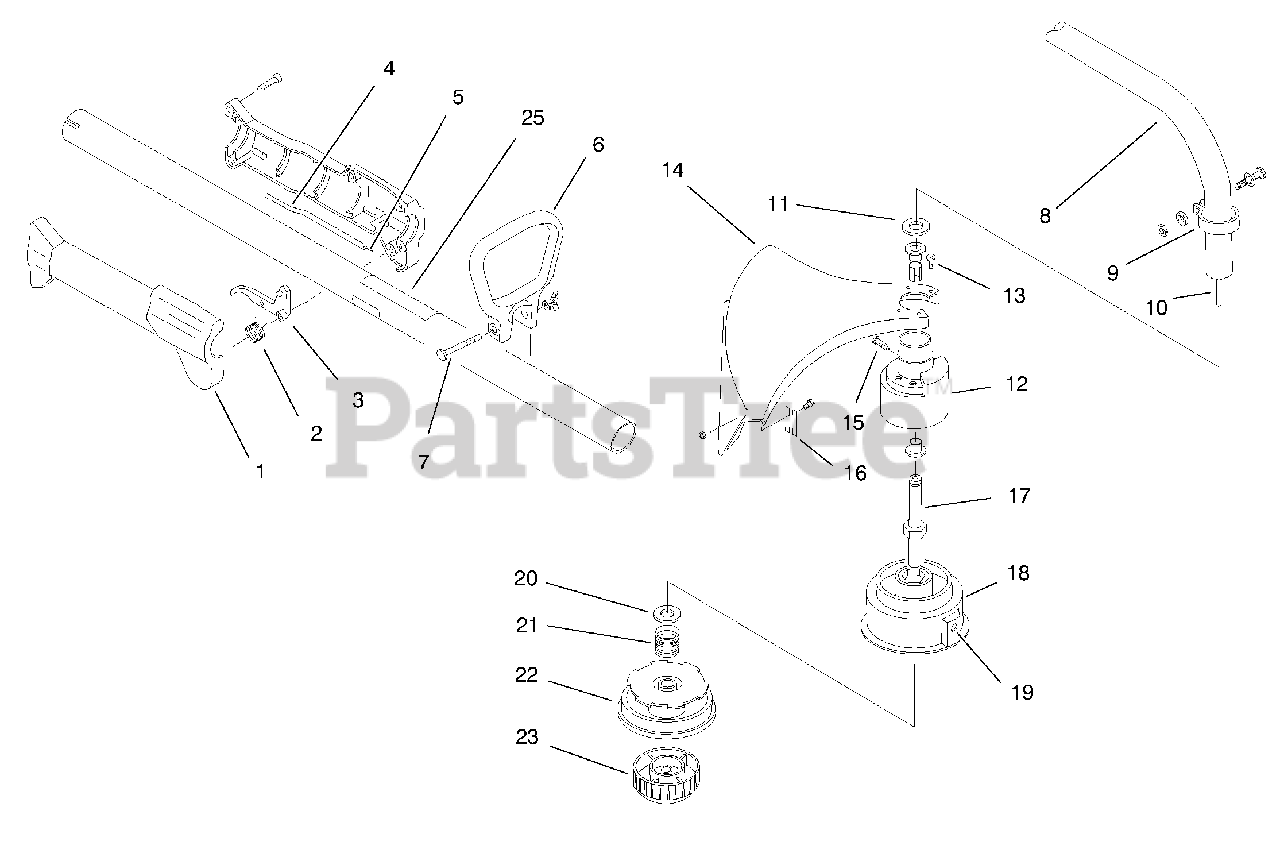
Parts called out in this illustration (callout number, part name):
1	Throttle Housing & Trigger Asm.
2	Throttle Trigger Spring
3	Throttle Trigger
4	Throttle Cable Housing
5	Throttle Cable
6	D-Handle
7	D-Handle Hardware Asm.
8	Drive Shaft Housing Asm.
9	Clamp Asm.
10	Flexible Drive Shaft
12	Bushing Housing Asm.
13	Guard Mounting Screw Asm.
14	Guard and Blade Asm. (Incl. Ref. #16)
15	Anti-Rotation Screw
16	Blade Asm.
17	Spool Shaft
18	Outer Spool and Eyelet Asm.
20	Retainer
22	Inner Reel
23	Bump Head Knob Asm.
25	Decal-Safety Symbols
